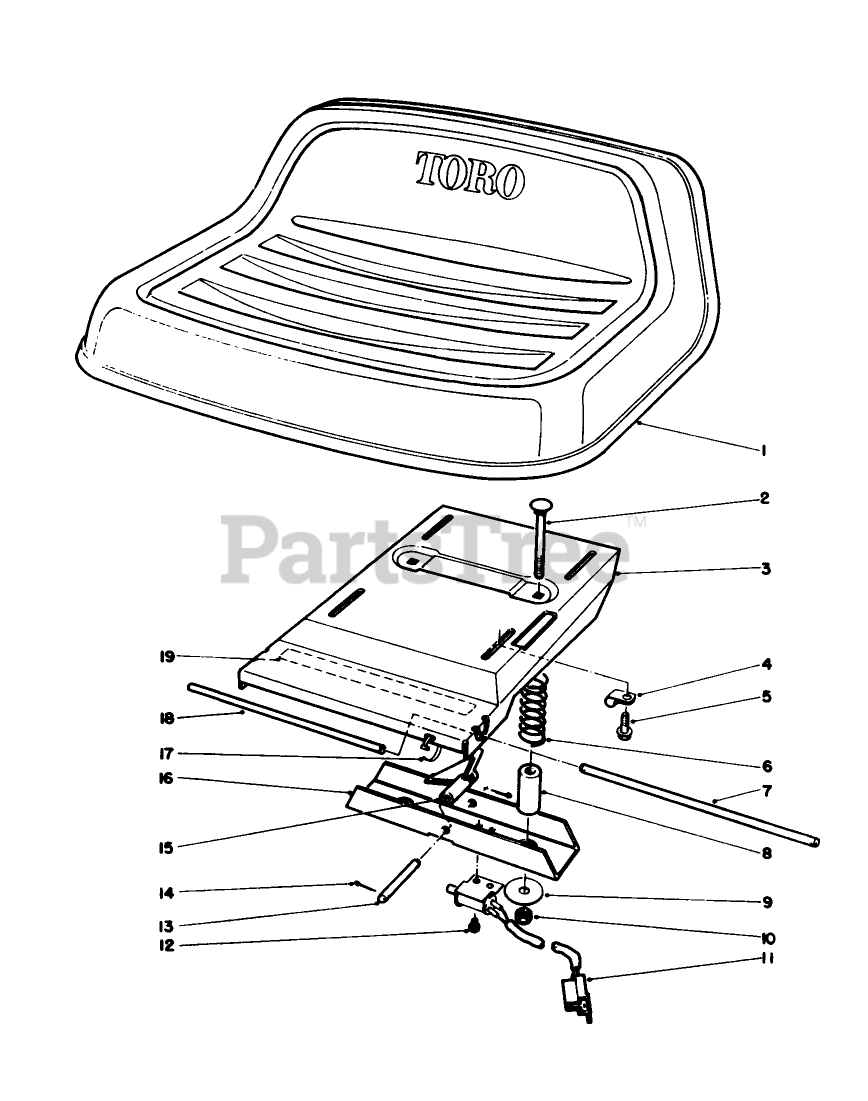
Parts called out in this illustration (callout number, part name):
2	BOLT-CARR
4	CLAMP
5	SCREW-HHF
7	SEAT BASE ROD
9	WASHER-FLAT
10	NUT-LOCK, NI
12	SCREW-TAPTITE
14	Cotter Pin
15	LEVER SWITCH
17	TIE-CABLE
18	TUBE-SEAT
